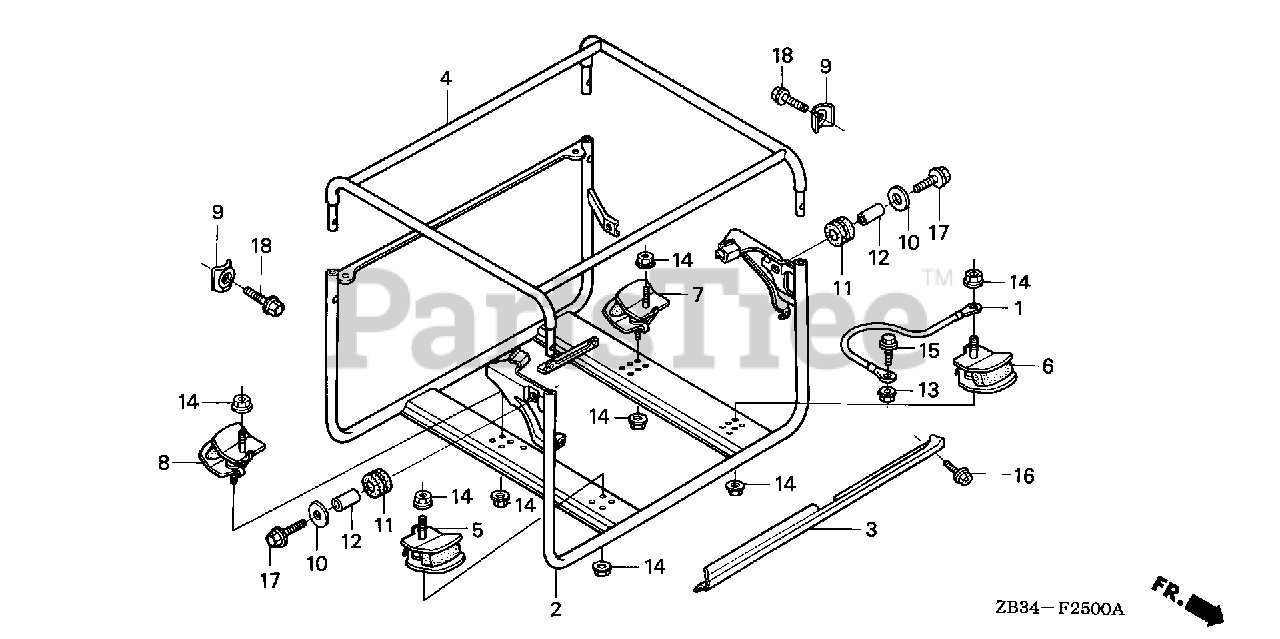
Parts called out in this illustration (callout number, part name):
1	CABLE, GROUND
2	FRAME (LOWER)
3	CHANNEL, FR.
4	FRAME (UPPER) (NOT AVAILABLE)
5	RUBBER (LOWER)
6	RUBBER (LOWER)
7	RUBBER, FR. (LOWER) (NOT AVAILABLE)
7	RUBBER, FR. (LOWER)
8	RUBBER, RR. (LOWER)
9	WASHER, FRAME JOINT
10	WASHER, FLAT (20MM)
11	RUBBER, CONTROL BOX
12	COLLAR, CONTROL BOX
13	NUT, FLANGE (6MM)
14	NUT, FLANGE (8MM)
15	BOLT, FLANGE (6X10)
16	BOLT, FLANGE (6X12)
17	BOLT, FLANGE (6X20)
18	BOLT, FLANGE (8X20)
